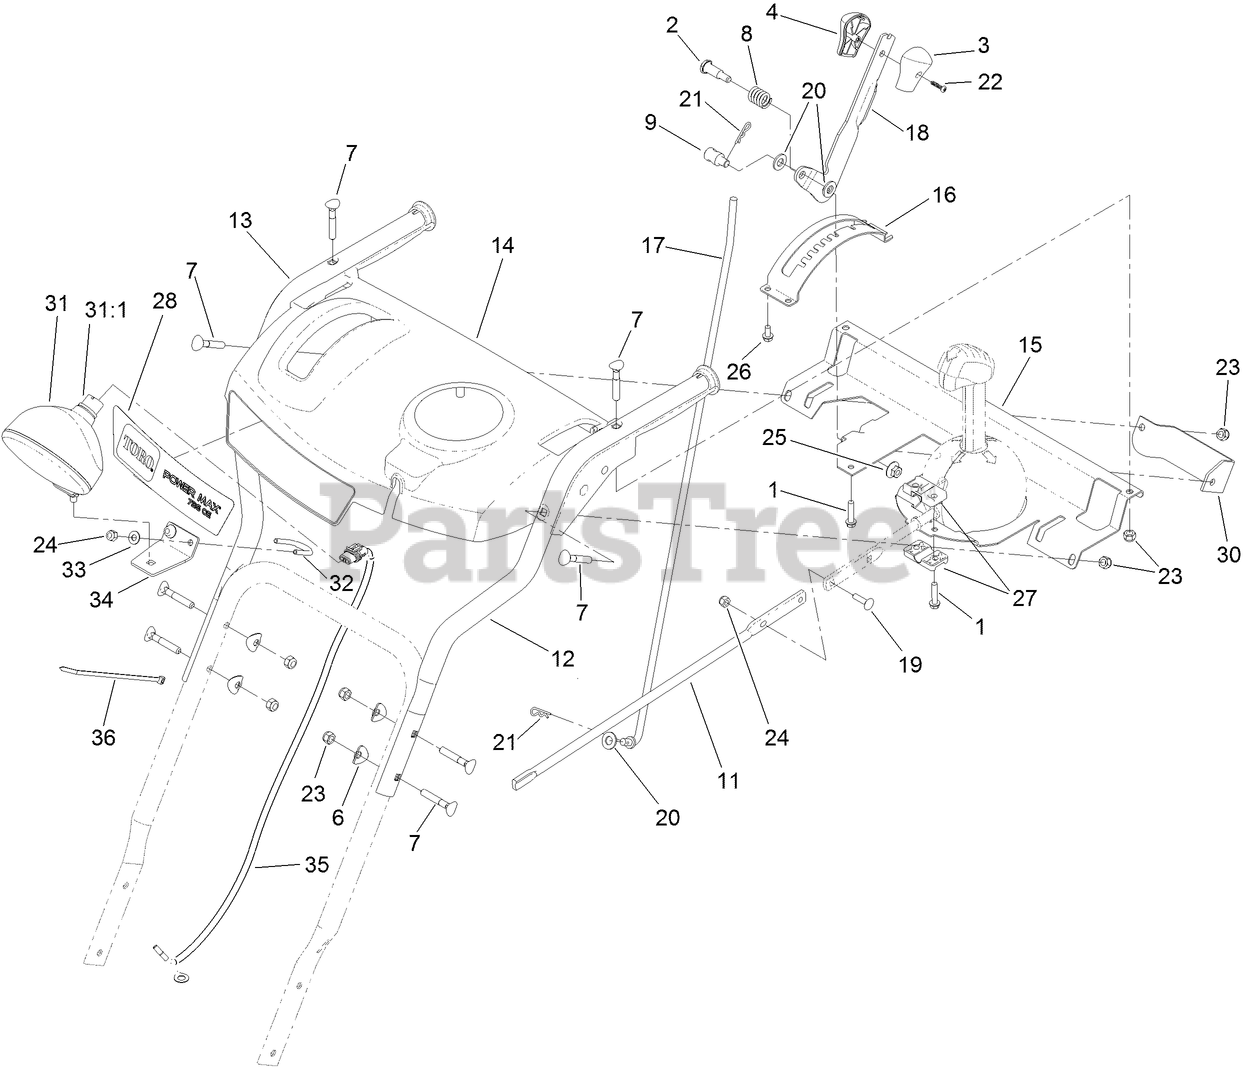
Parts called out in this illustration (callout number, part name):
1	SCREW-PLASTITE
2	SCREW-SHOULDER
3	KNOB-SHIFT, LH
4	KNOB-SHIFT, RH
6	WASHER
7	SCREW-HANDLE
8	SPRING-COMPRESSION
9	TRUNNION-ROD
11	ROD-CHUTE, FRONT
12	HANDLE-UPPER, LH
13	HANDLE-UPPER, RH
14	PANEL-CONTROL, MASTER
15	SUPPORT-PANEL, CONTROL
16	MOUNT-SELECTOR, SPEED
17	ROD-SELECTOR, GEAR
18	SELECTOR-SPEED
19	SCREW-CARR
20	WASHER-FLAT
22	SCREW-PPH
23	NUT-LOCK, NI
24	NUT-LOCK, NI
25	NUT-HF
26	SCREW-PLASTITE
27	SUPPORT-ROD
28	DECAL-PANEL, CONTROL
30	PLATE-SUPPORT, SHIFT
31	HEADLAMP ASM
31:1	LAMP-12 VOLT
32	CLAMP-LIGHT
33	WASHER-FLAT
34	BRACKET-LIGHT
35	HARNESS-WIRE
36	TIE-CABLE
